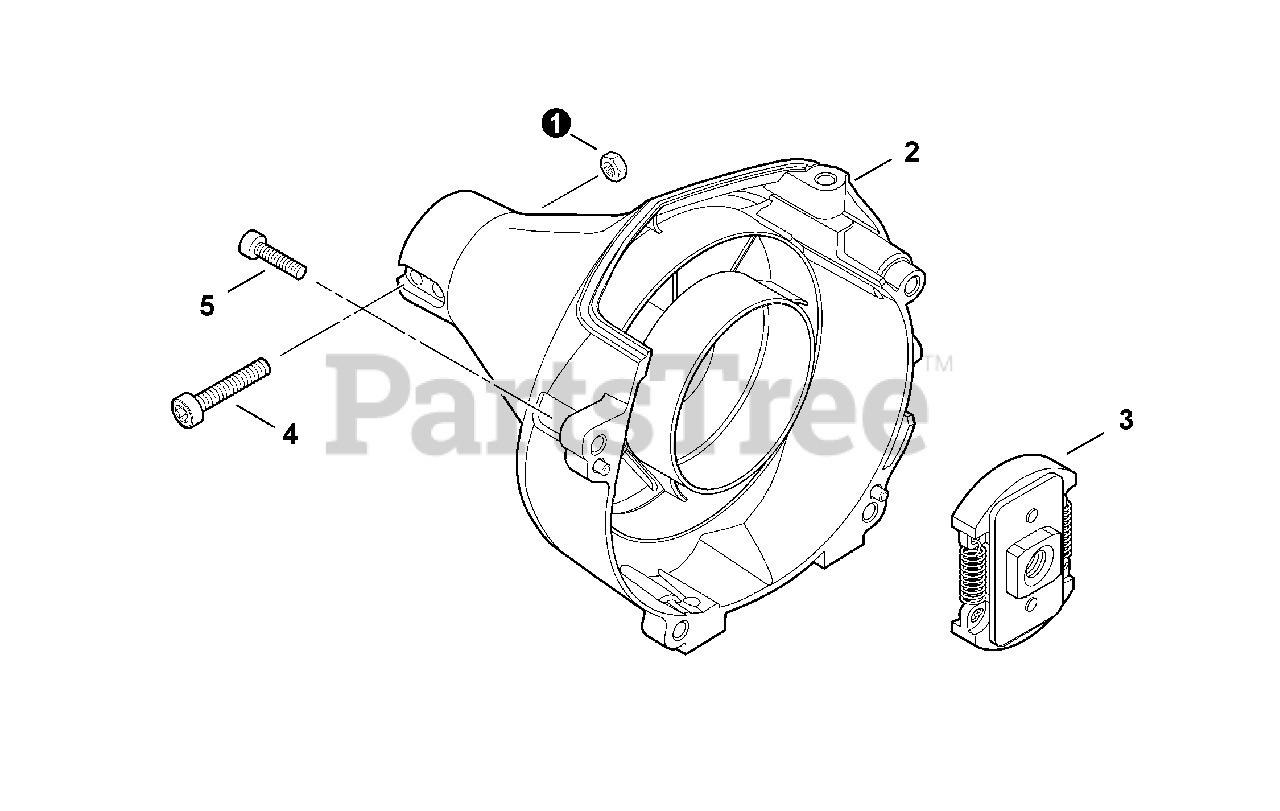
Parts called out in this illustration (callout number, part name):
2	COVER ASSY, FAN
3	CLUTCH ASSY
4	BOLT, TORX 5×25
5	BOLT, TORX 4×16
